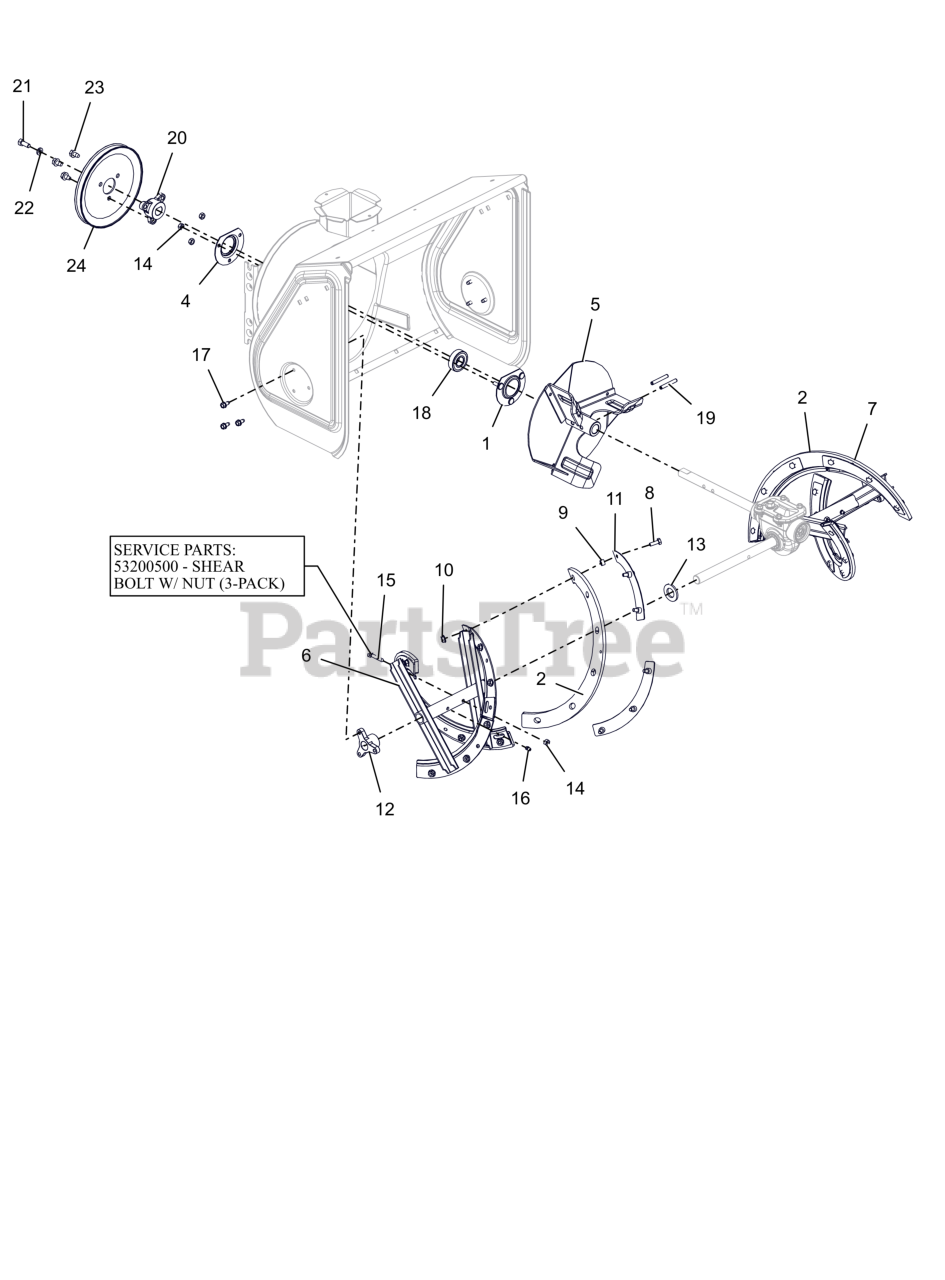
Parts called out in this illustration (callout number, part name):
1	BEARING FLANGE
2	KIT, RUBBER FLIGHTING RAKE
4	BEARING FLANGE
5	IMPELLER, 10" 3-BLADE LG BACK (BLACK)
6	WLDMT, AUGER 20" GROUND - RH (BLACK)
7	WLDMT, AUGER 20" GROUND - LH (BLACK)
8	BLT, HEX .25-20X.75 G5 ZCC
9	BUSHING, .26 ID X .44 OD X .26
10	NUT-LK-CTR-FLG .25-20 ZC120
11	BRACE, RUBBER FLIGHTING (BLACK)
12	BUSHING, RAKE SHAFT .75"
13	WSHR, FLT .812X1.469X.134 ZCC
14	NUT,LK-CTR .25-20 GA ZCC
15	SHEAR BOLT WITH NUT
16	ZERK,FITTING .25X.125 DRIVE IN
17	SCR-TAP .25-20X.50 HWH ZCC
18	BRG-BALL .750X1.750X.50
19	PIN-ROLL .250X1.75
20	PULLEY HUB, BOLT-ON D-BORE .75
21	BLT, HEX .31-24X.750 G5 ZCC
22	WSHR, LK-HVY .312X.097 ZCC
23	SCR,TAP .312-18X.50 HWH TR ZCC
24	PULLEY, V 7.000 X 1.375 3BLT
